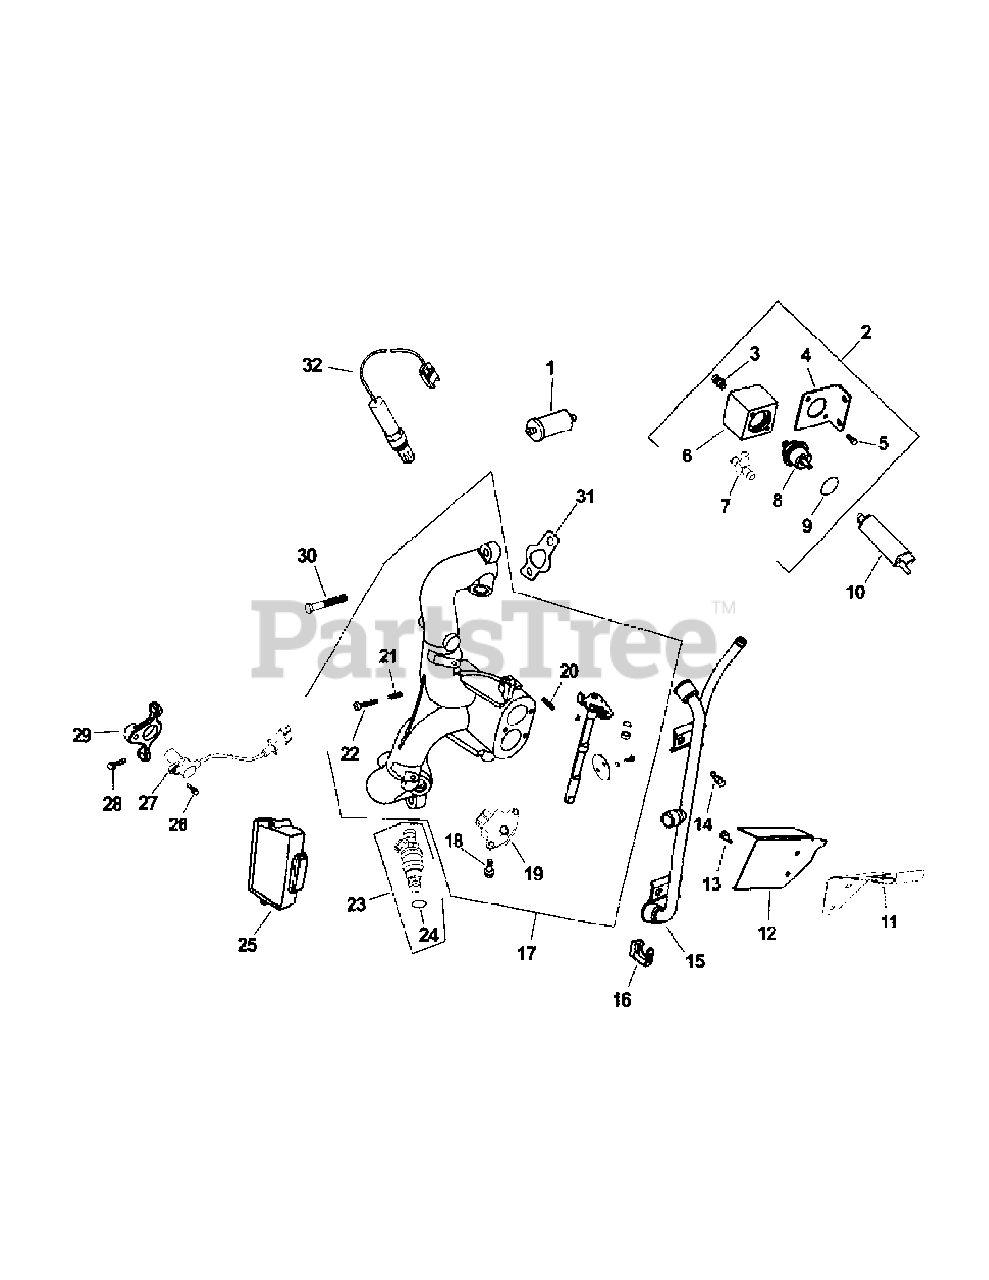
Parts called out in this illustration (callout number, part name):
1	Fuel Filter, EFI, High pressure
2	Fuel Pressure Reg. Assy.
3	Barbed Fitting
4	Regulator Bracket
5	Hex Head Screw
6	Regulator Housing
7	Tee Fitting
8	Pressure Regulator
9	O-Ring
11	Valley Baffle
12	Air Deflector
13	Hex Flange Screw
14	Hex Flange Screw
16	Fuel Injector Clip
17	Intake Manifold
18	Throttle Position Sensor
19	Pan Head Screw
21	Speed Control Spring
22	Pan Head Screw
23	Fuel Injector
25	Engine Management Module
27	Speed Pickup Sensor
28	Hex Flange Screw
29	Speed Sensor Bracket
30	Hex Flange Screw
31	Intake Manifold Gasket
32	Oxygen Sensor
